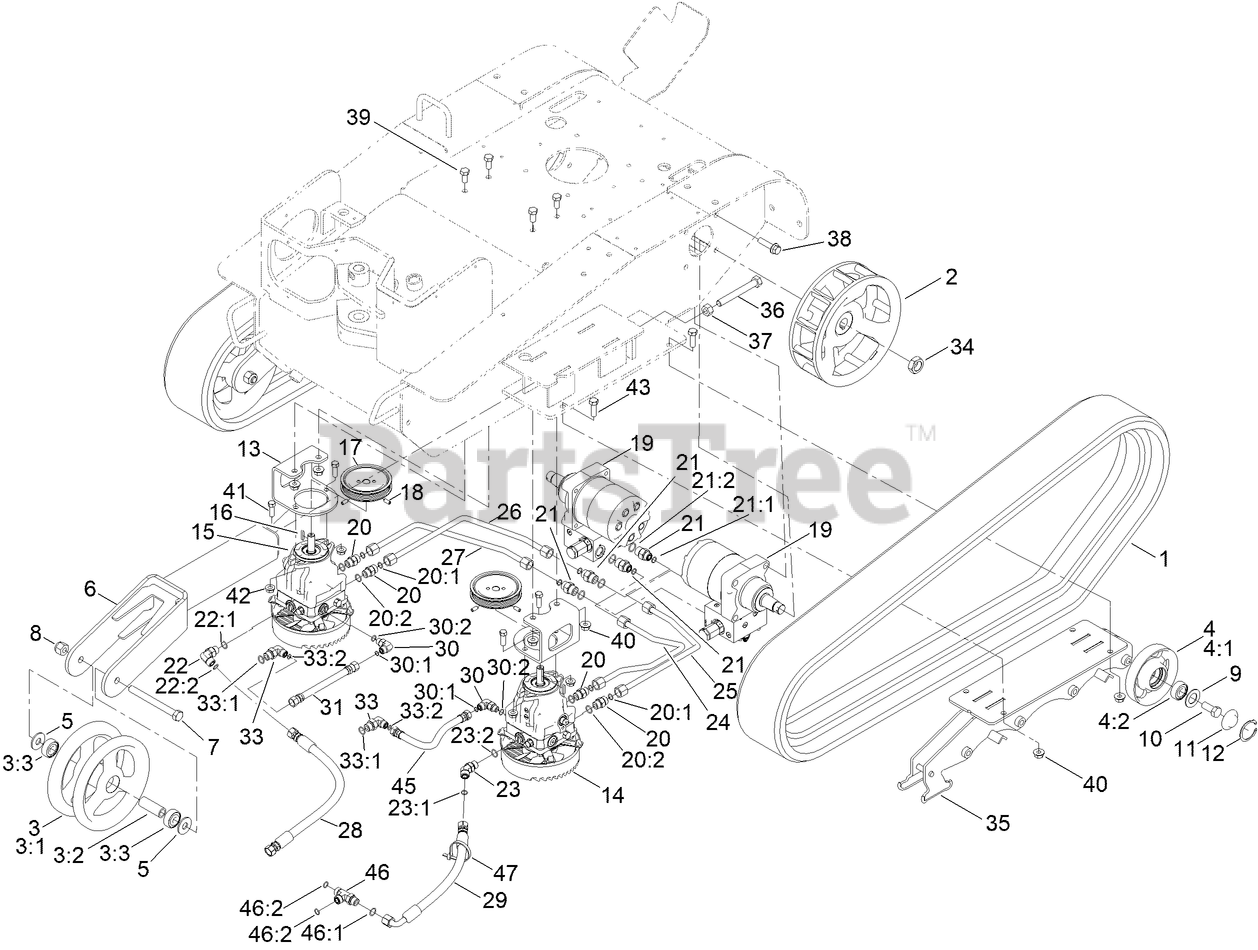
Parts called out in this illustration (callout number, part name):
1	TRACK-RUBBER
2	WHEEL-DRIVE
3	TENSIONER WHEEL ASM
3:1	WHEEL-TENSIONER
3:2	SPACER-WHEEL, TENSIONER
3:3	BEARING-BALL
4	TENSIONER WHEEL ASM
4:1	WHEEL-TRACK
4:2	BEARING-BALL
5	WASHER-FLAT
6	ARM-TENSIONER
7	SCREW-HH
8	NUT-HEX
9	GASKET-BOGIE
10	SCREW-HH
11	CAP-WHEEL, BEARING
12	RING-SNAP, INTERNAL
13	BRACKET-MOUNT, PUMP
14	PUMP-HYD, LH
15	PUMP-HYD, RH
16	KEY-PUMP
17	SHEAVE
18	SCREW-SET, HSH
19	HYD MOTOR ASM
20	FITTING-STRAIGHT
20:1	O-RING
20:2	O-RING
21	FITTING-STRAIGHT
21:1	O-RING
21:2	O-RING
22	FITTING-ELBOW, 90 DEG
22:1	O-RING
22:2	O-RING
23	FITTING-HYD, 45 DEG
23:1	O-RING
23:2	O-RING
24	TUBE-HYD
25	TUBE-HYD
26	TUBE-HYD
27	TUBE-HYD
28	HOSE-HYD
29	HOSE-HYD
30	FITTING-ELBOW, 90 DEG
30:1	O-RING
30:2	O-RING
33	FITTING-HYD, 90 DEG
33:1	O-RING
33:2	O-RING
34	NUT-LOCK
35	MOUNT-WHEEL
36	SCREW-HH, TAP
37	NUT-HEX
38	SCREW-HHF
39	SCREW-HH
40	NUT-HHF
41	SCREW-HH
42	NUT-HF
43	SCREW-HH
45	HOSE ASM-HYD LP
46	FITTING-TEE
46:1	O-RING
46:2	O-RING
47	TIE-CABLE
